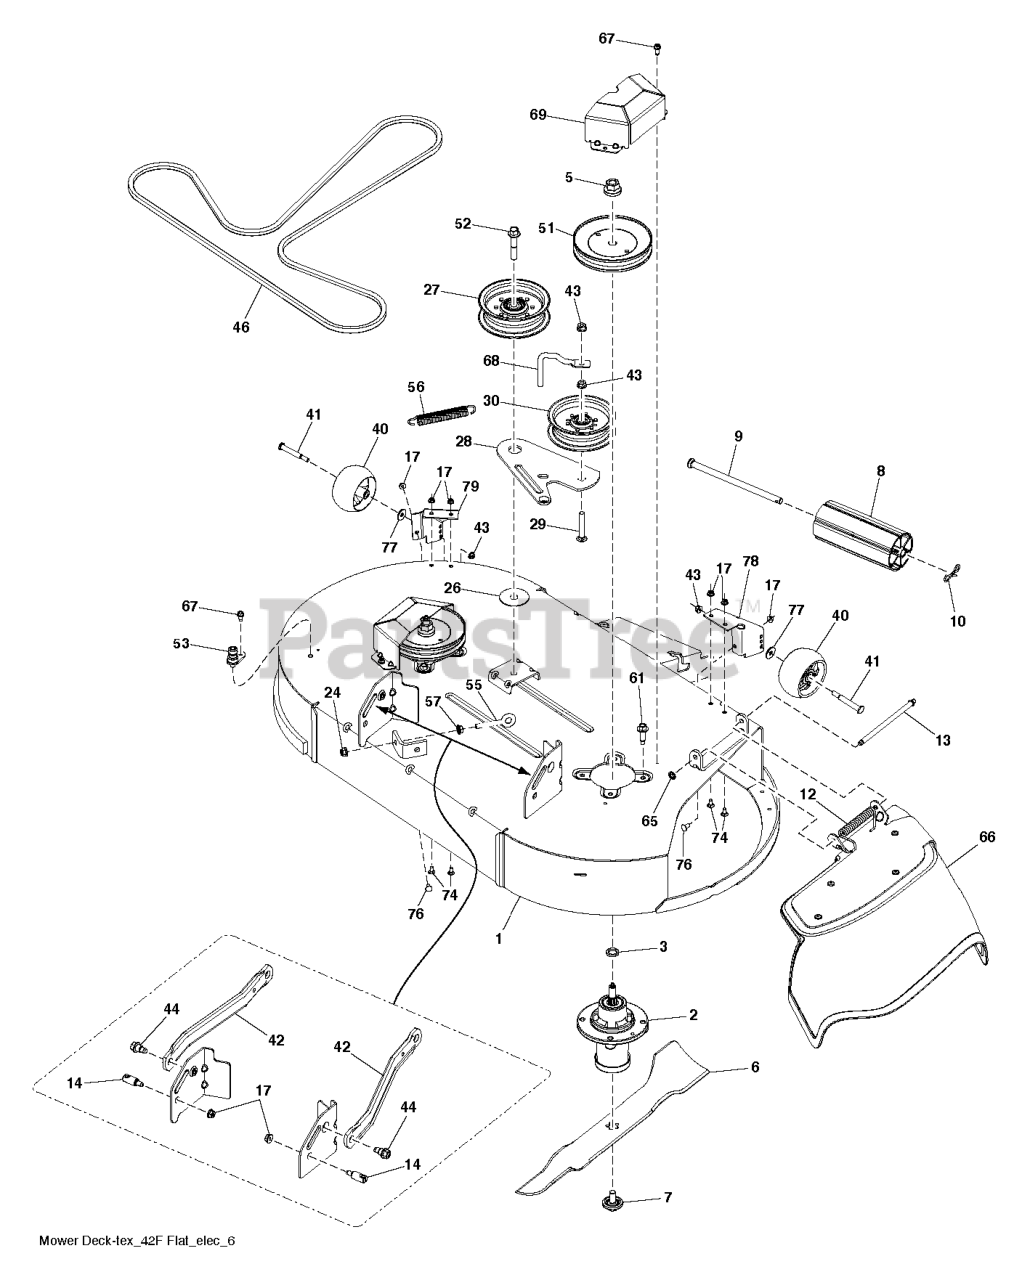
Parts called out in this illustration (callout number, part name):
1	DECK SVC.42F.668
2	MANDREL.DECK.ASSEMBLY
3	WASHER.SPACER.MANDREL
5	LOCKNUT - 9/16
6	BLADE.42.FCS.BAGGING.BLADE.RAW
7	BOLT.WASHER.ASM.7/16-2
8	NOSE ROLLER 48"
9	ROD.ROLLER.NOSE.NARROW.48"
10	PIN.COTTER.5/16.BOW TI
12	SPRING.42.FCS.DEFLECTOR
13	ROD.HINGE
14	STUD.FASTNER.W/ANTI-ROTATE
17	NUT LOCK HEX FLANGE 5/16-18
24	5/16-18 NYLOC FLANGE NUT
27	PULLEY.IDLER.MWR.STATI.LH
28	ARM.42"FCS.CLUTCHING.X431
29	BOLT
30	PULLEY.IDLER.2006
40	RP WHEEL. GUAGE RALLY
41	BOLT.SHOULDER.3/8-16X3-5/8.
42	ARM.SUSPENSION.MOWER
43	NUT LOCK FLG 3/8-16 UNC
44	BOLT.SHOULDER
46	BELT.42.FCS.TRACTOR.DECK.DRIVE
51	PULLEY MANDREL 5.0"
52	SCREW.7/16-14 X 2.125.WASHER
53	PORT.WASHOUT
55	EYE BOLT 5/16 X 3.50
56	SPRING.EXTN.42.FCS.TR.DECK.DRV
57	NUT 5/16C WHIZ
61	BOLT.HEX.WASHR.HED.313-18X1.19
65	NUT PUSH M
66	DEFLECTOR.42".FCS
67	SCREW.1/4-20X5/8
68	KEEPER.BELT.IDLER.54"T
69	COVER.42".MANDREL.FCS.PNT.498
74	BOLT.CARR.5/16-18X5/8.SHORT
75	BUMPER.2FCS.CLCT.TRIM.SIDE.BLK
76	NUT ACORN,FLANGED,5/16-18
77	WASHER
78	BRACKET.PNT.GA-WHEEL.FCS.42.RH
79	BRACKET.PNT.GA-WHEEL.FCS.42.LH
